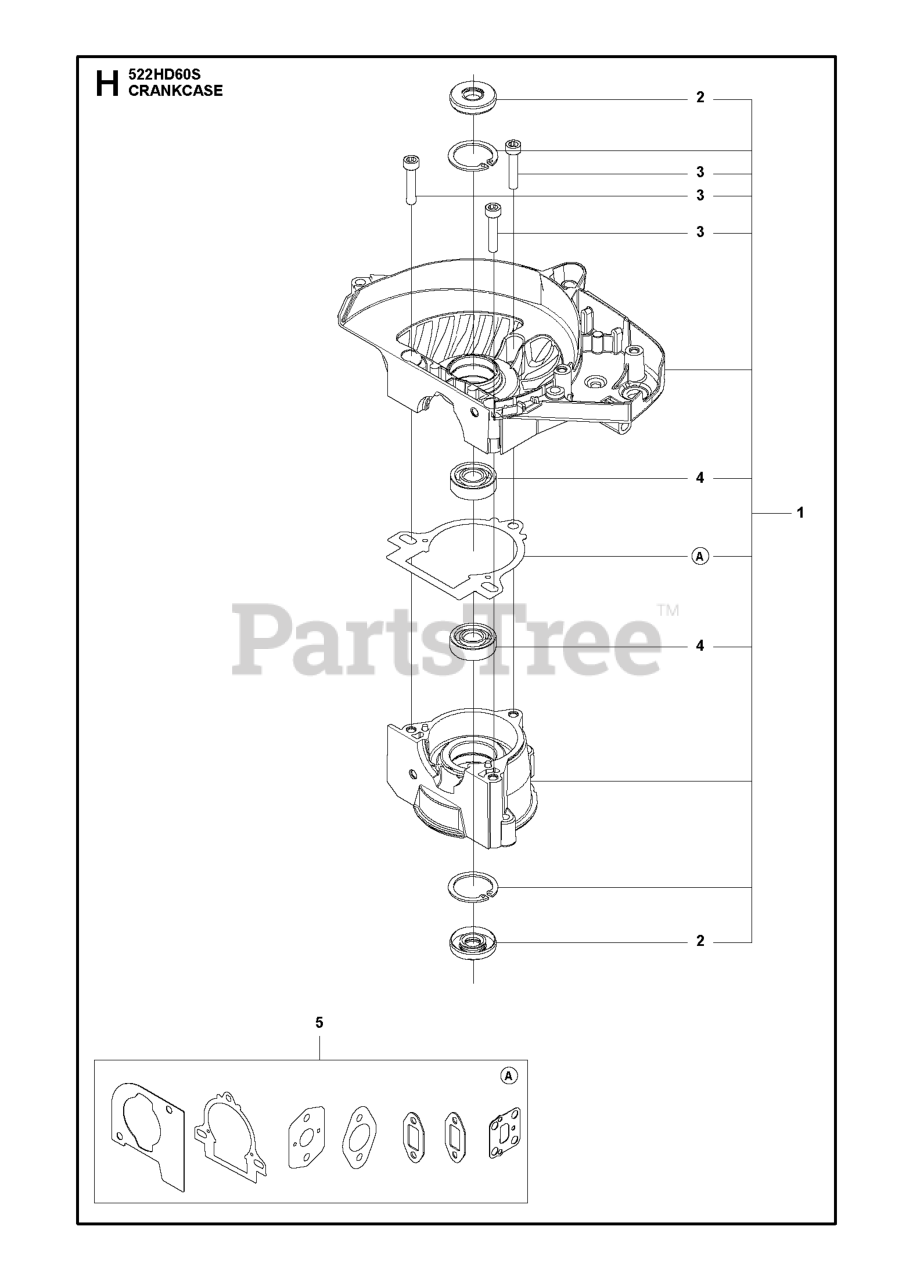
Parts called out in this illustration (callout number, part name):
1	CRANKCASE ASSY KIT 522
2	SEALING RING
4	BALL BEARING
5	GASKET KIT 522
